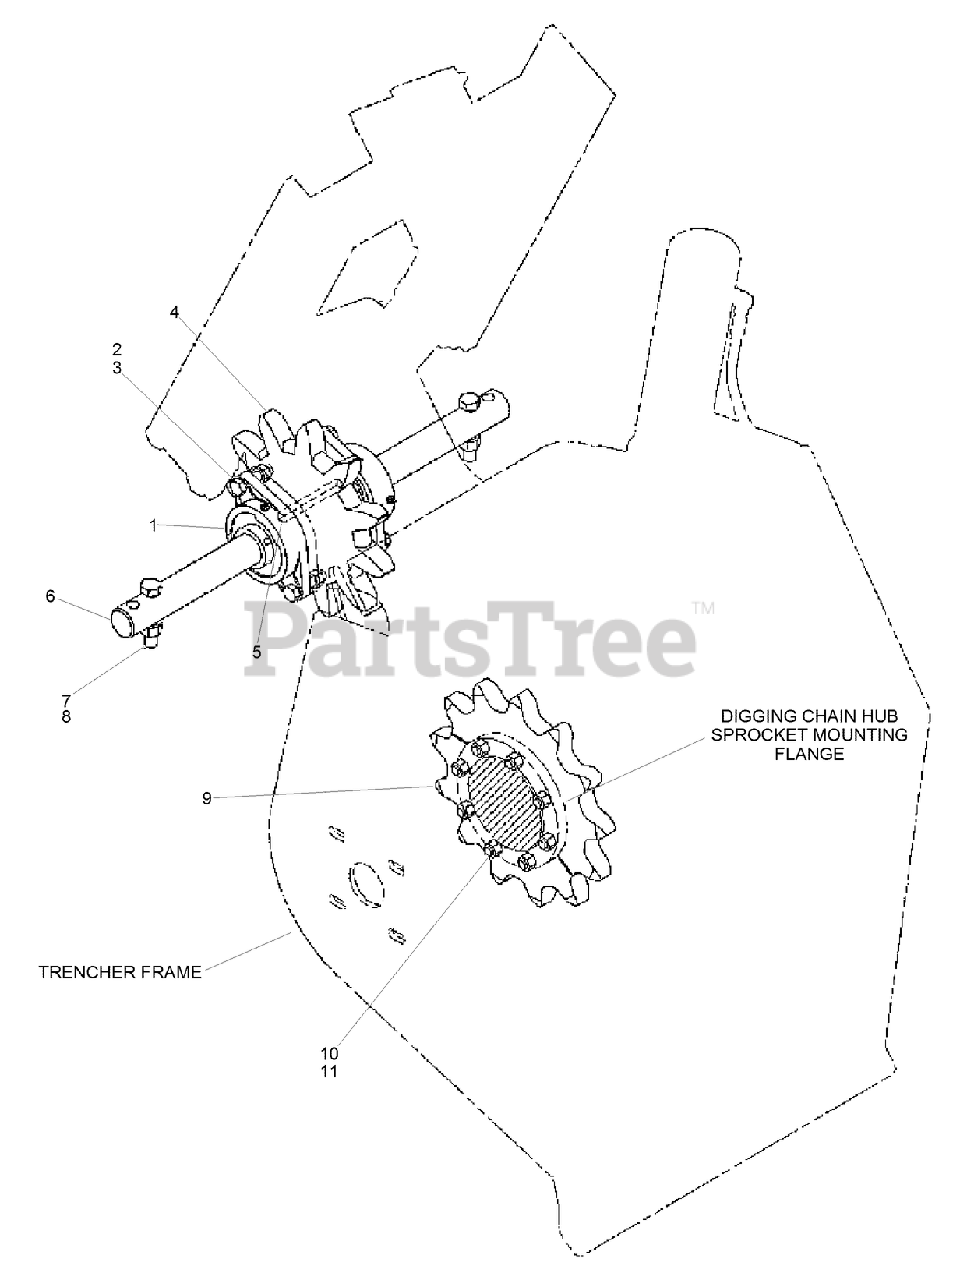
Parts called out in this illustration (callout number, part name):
1	BEARING-BALL, 2-BOLT FLANGE (2 IN)
2	BOLT - 5/8 x 2-1/2
3	NUT-LOCK, HEX
4	SPROCKET - Auger Drive, 311 Chain
5	KEY-SQUARE
6	SHAFT-AUGER
8	NUT-Prev Trq 3/4 GRC CAD Direct
9	SPROCKET - Split, 311 Chain
10	SCREW-HH
11	NUT-HEX
